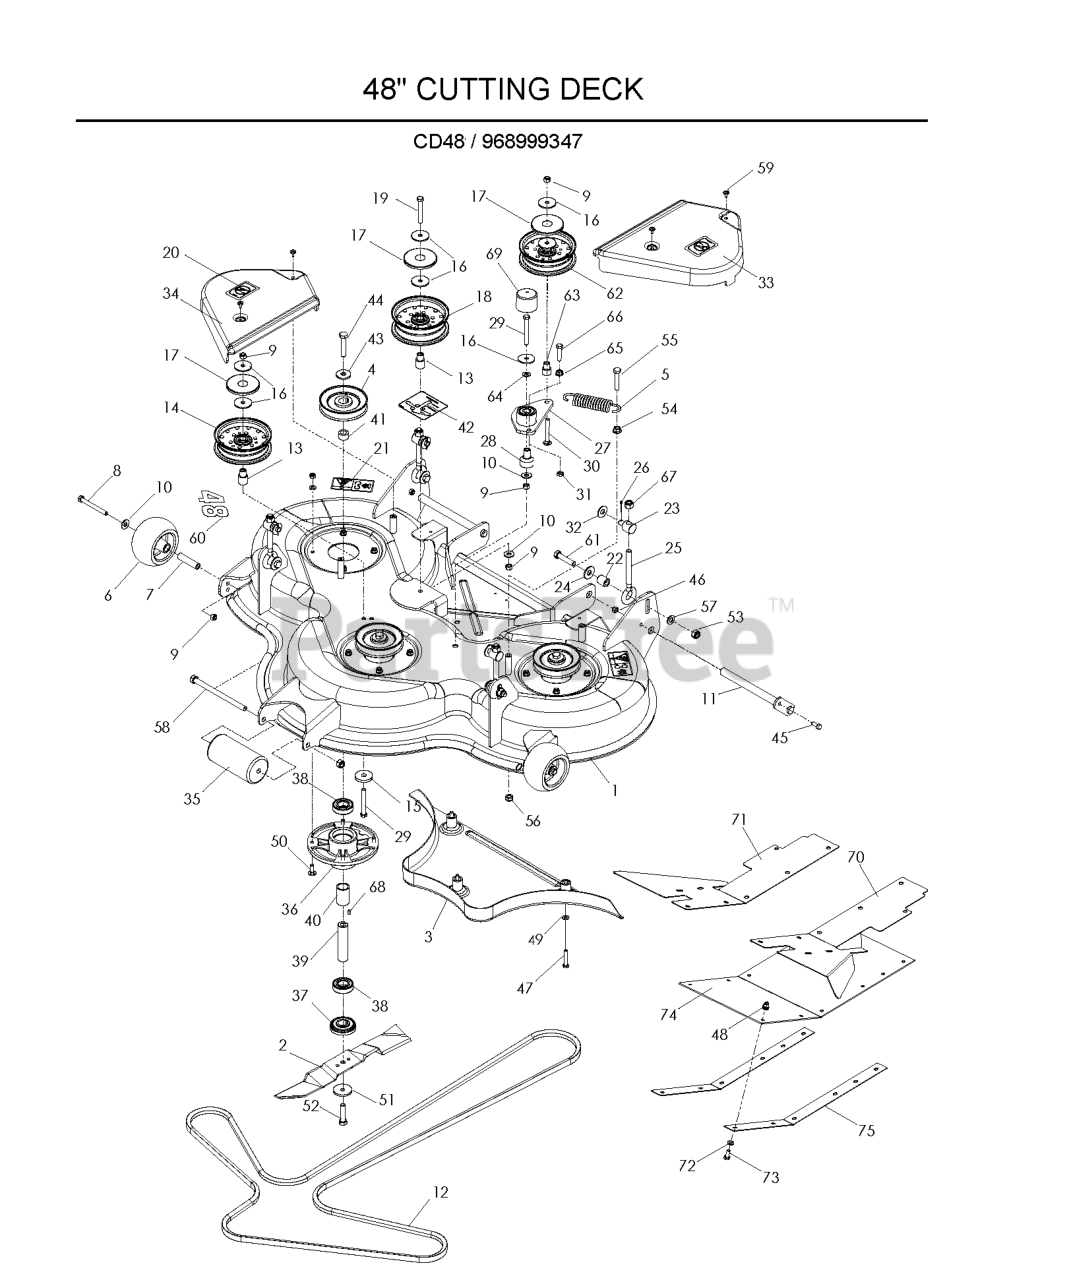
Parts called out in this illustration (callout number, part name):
4	PULLEY, 48
6	ANTI-SCALP ROLLER
8	HCS 3/8C X 3 1/2
9	NUT 3/8-16 NYLOC
10	WASHER 3/8 FLAT
12	DECK BELT, 48 CMB
13	IDLER BUSHING
14	IDLER PULLEY
15	SPINDLE WASHER
16	WASHER, 3/8 SPEC
17	TOP DUST CAP
18	IDLER PULLEY (TALL)
19	SCREW 3/8C X 2 3/4 HEX CAP
20	DECAL, NO STEP
21	DECAL, BELT DRIVE
24	SPRING WASHER - .50
26	PIN COTTER 1/8 X 1 ZD
27	ARM-IDLER W/BRG
28	PIVOT, BEARING
29	HCS 3/8C X 3
30	RHSNB 3/8-16 X 2.75
31	NUT 3/8-16 HEX JAM
32	WASHER 1/2 FLAT
33	BELT SHIELD LT
34	BELT SHIELD RT
35	ROLLER
36	BEARING HOUSING
38	BALL BEARING
41	KEY RETAINER
42	DECAL, BELT ROUTING
45	SCREW 8X20
46	LOCKNUT M8
47	SCREW
49	WASHER BRB 8.4X17
56	NUT
57	WASHER - M12
62	IDLER PULLEY
63	BUSHING, IDLER
64	WASHER 3/8 SAE FLAT
65	NUT 3/8C WHIZ
66	HCS 3/8-16 X 1-1/2
67	NUT 1/2-13 HEX NYLOC ZD
69	CAP, VINYL
71	DECAL, BZ34
72	WASHER - 15X7.3X1.6
73	SCREW 8X20
